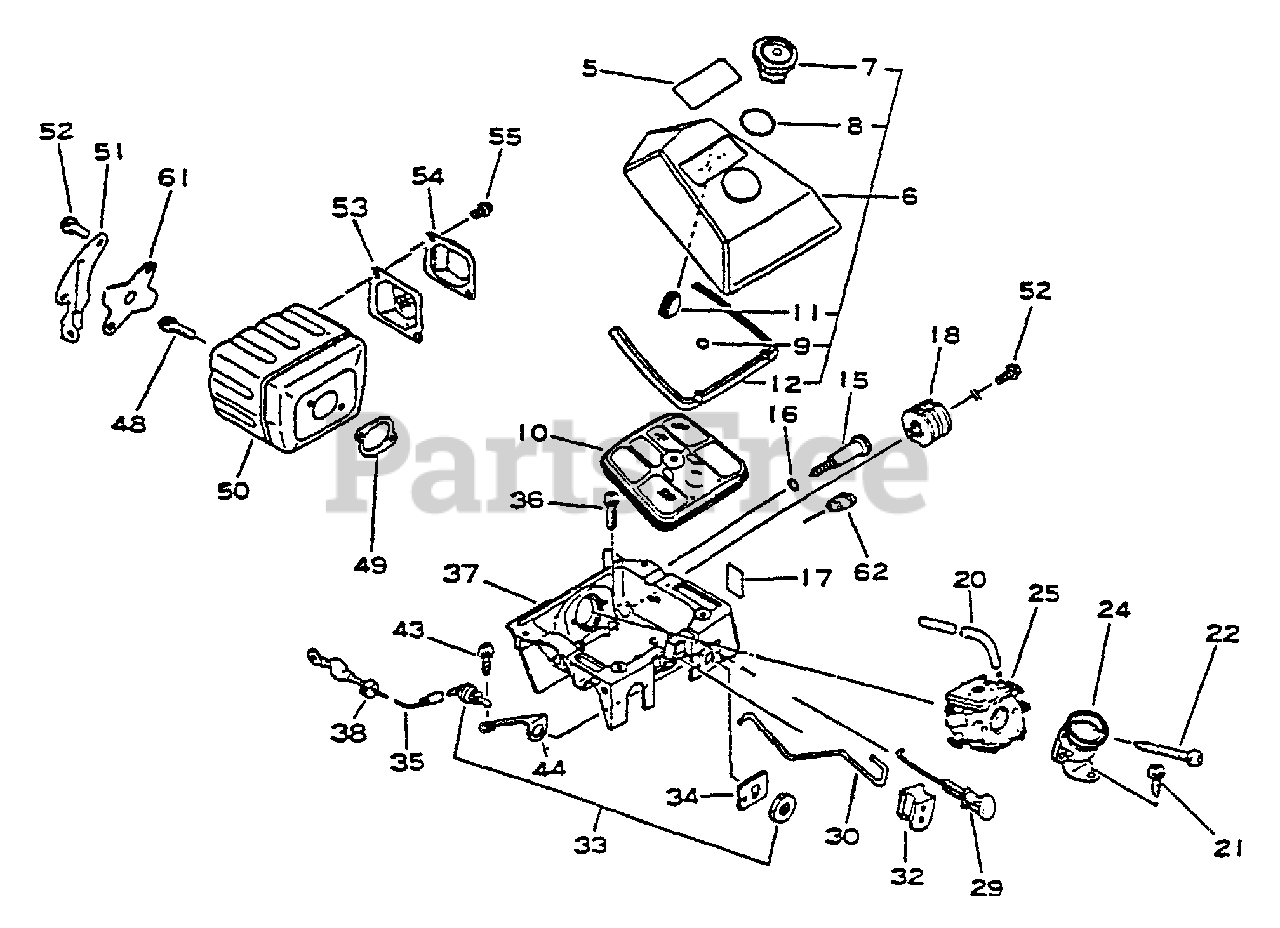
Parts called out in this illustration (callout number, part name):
5	LABEL
6	COVER ASSY, AIR FILTER
7	THUMBSCREW
8	O-RING 22
9	O-RING P-11
10	FILTER ASSY, AIR
12	GASKET, AIR FILTER
15	SCREW, IDLE ADJUST - ORANGE
16	O-RING 7 MM
17	LABEL, CAUTION - IDLE
18	CUSHION
20	FUEL PIPE KIT
21	SCREW - 5×14
22	SCREW 5×53
24	ADAPTOR, INTAKE
25	CARBURETOR
29	ROD, CHOKE
30	ROD, THROTTLE
32	GROMMET, THROTTLE ROD
33	SWITCH, ON-OFF
34	LABEL, STOP
35	LEAD - GROUND
36	SCREW 5×20
37	CASE, CARBURETOR
43	SCREW 4×10
44	PLATE, GROUND
48	SCREW - 5×20
49	GASKET, EXHAUST
50	MUFFLER
51	BRACKET, MUFFLER
52	SCREW - 5×14
53	SCREEN, SPARK ARRESTER
54	COVER, MUFFLER
55	SCREW 4×10
61	COVER, MUFFLER
